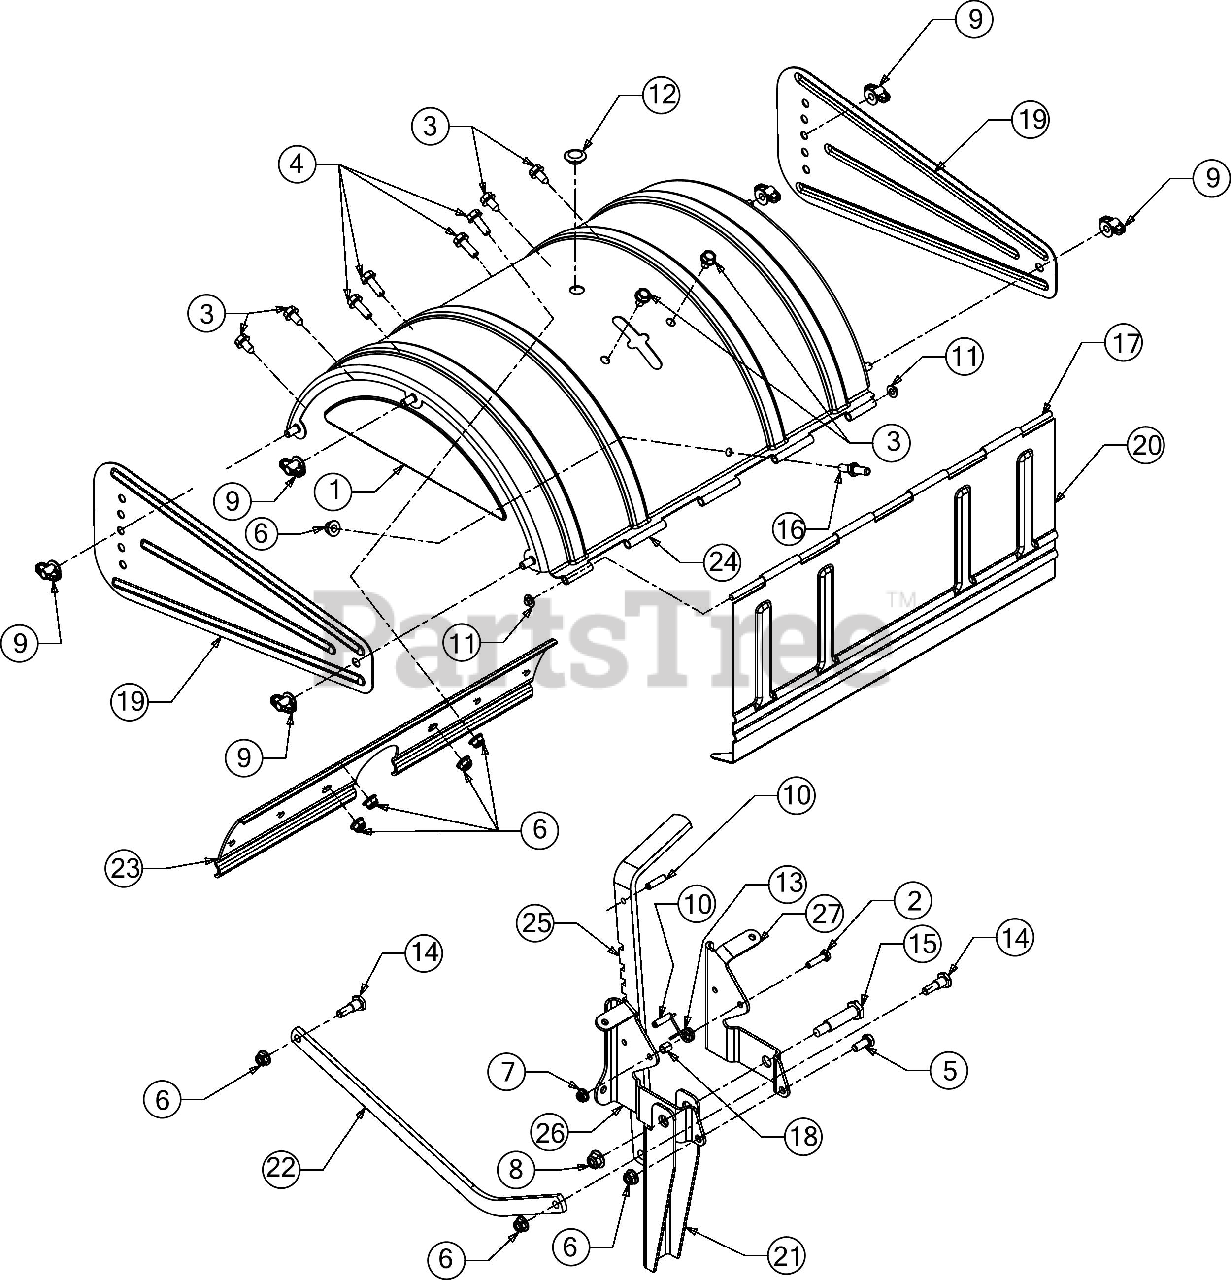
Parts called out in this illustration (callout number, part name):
1	END COVER ASSEMBLY
1	CLINCH STUD 5/16-18 X .75
2	SCREW 1/4-20 X1.00 GR5
3	SCREW 5/16-18 X .625
4	SCREW 5/16-18 X .875 GR5
5	SCREW 5/16-18 x .75 GR5
6	FLANGE LOCK NUT 5/16-18
7	FLANGE LOCK NUT
9	WING NUT 5/16-18
10	SPRING PIN 1/4 X 1.00
11	PUSH NUT
12	DECK HOLE PLUG
13	TORSION SPRING
14	SHOULDER SCREW
15	SHOULDER BOLT .498 X 1.635:3/8-16
16	SHOULDER SCREW
17	TILLER FLAP ROD
18	ROUND SPACER
20	REAR TINE SHIELD
21	REVERSE STOP ARM
22	DEPTH DRAG BAR
25	DEPTH ADJUSTMENT BRACKET
26	TAIL BRACKET (LH)
27	TAIL BRACKET (RH)
